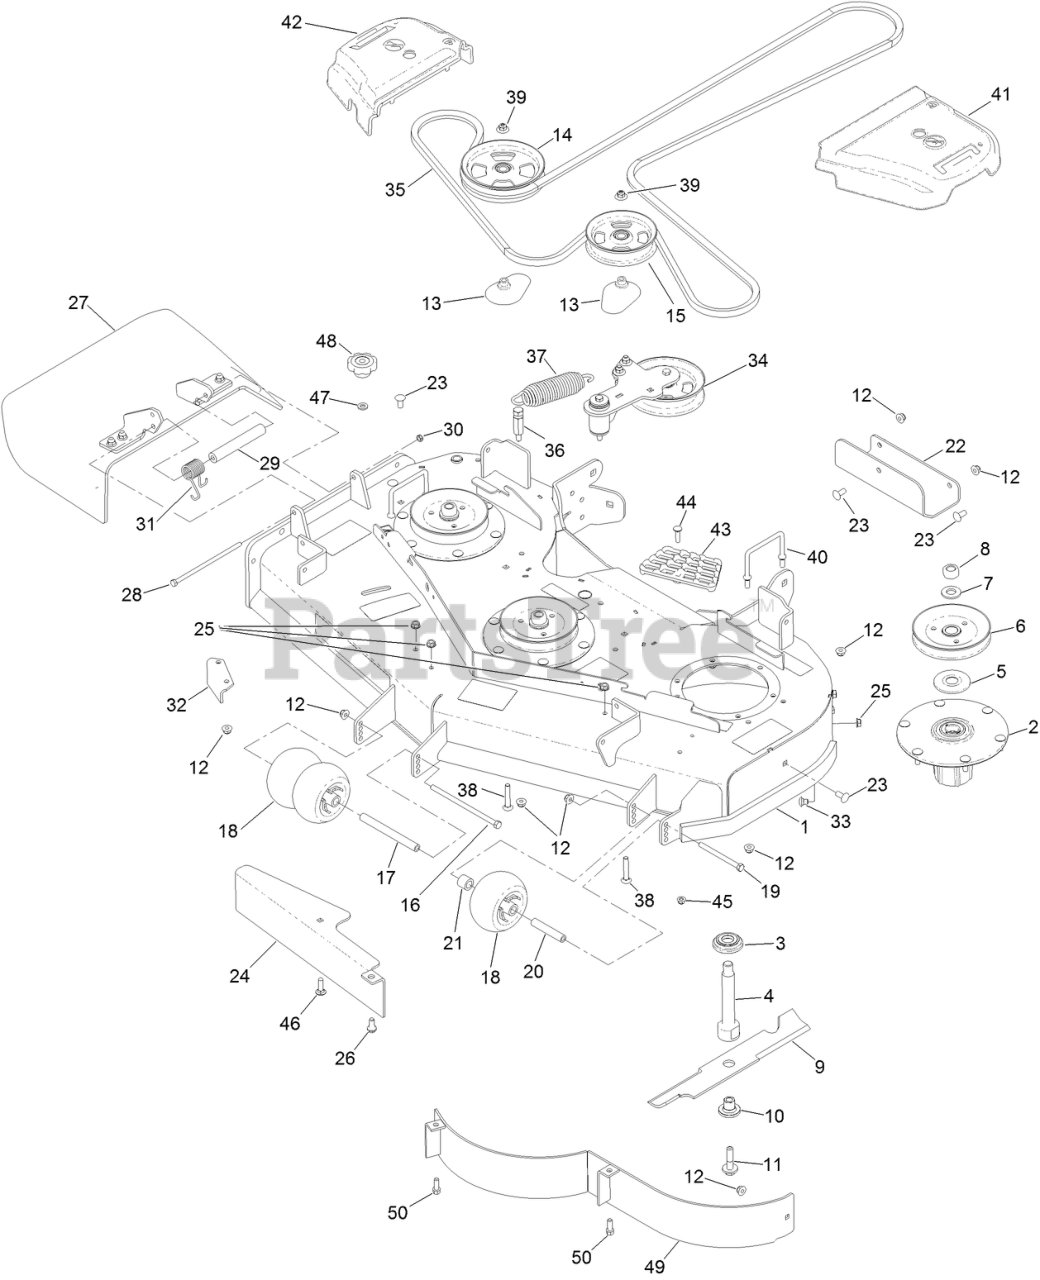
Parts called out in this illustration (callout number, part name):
1	DECK DECAL ASM
2	SPINDLE ASM
3	GUARD-BOTTOM
4	SHAFT-SPINDLE
5	GUARD-BEARING, TOP
6	SHEAVE,BLADE DRIVE 5.91
7	WASHER
8	NUT-HEX
9	BLADE-16.50 HIGH FLOW
10	BUSHING-HEX
11	SCREW-SEMS
12	NUT-HF, NI
13	SPACER-PULLEY
14	PULLEY-IDLER, FLAT
15	PULLEY-IDLER,FLAT
16	SCREW-HH
17	SPACER-WHEEL
18	ROLLER-SCALP, ANTI
19	SCREW-HH
20	TUBE-SPANNER
21	TUBE-SPACER
22	PLATE-SKID
23	SCREW-CARR
24	PLATE-BAFFLE, FORMED
25	NUT-HHF, WHIZ
26	BOLT-SHOULDER
27	RUBBER DEFLECTOR ASM
28	SCREW-HH
29	SPACER
30	NUT-LOCK, NI
31	SPRING-TORSION
32	BAFFLE-DISCHARGE
33	SCREW-CARR
34	IDLER ARM ASM
35	BELT-V
36	ANCHOR-SPRING, TALL
37	SPRING-EXTENSION
38	BOLT-CARR, SHORT NECK
39	NUT-FLANGE, NI
40	WIREFORM-COVER
41	COVER-BELT, LH
42	COVER-BELT, RH
43	STEP-DECK
44	SCREW-CARR
45	NUT-HF, NI
46	BOLT-CARR
47	WASHER-HARDENED
